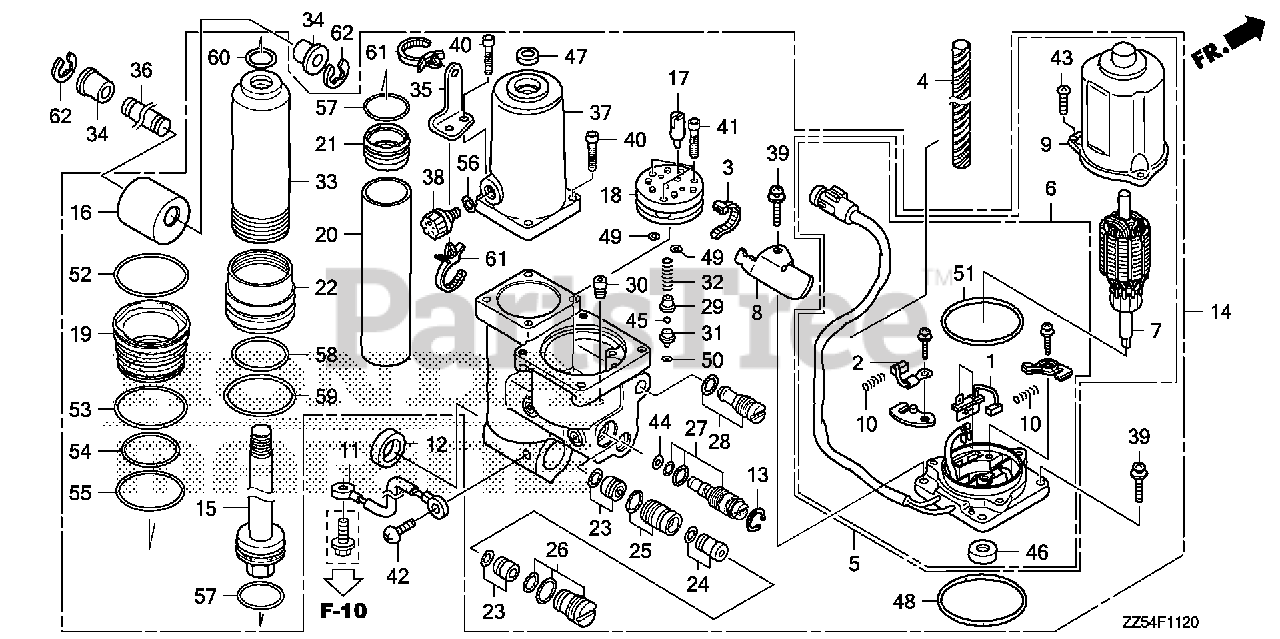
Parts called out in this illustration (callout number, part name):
1	BREAKER ASSY.
2	BRUSH ASSY.
3	BAND (BLACK 3.5X140)
4	TUBE, SPIRAL
5	MOTOR ASSY., POWER TILT
6	BRACKET ASSY.
8	CLAMP, WIRE
10	SPRING, MOTOR
11	WIRE, LEAD (1.5X116MM)
12	SPACER (19.4X6)
13	CIRCLIP (INNER) (16)
14	TRIM-TILT ASSY., POWER
15	ROD, PISTON
16	METAL, JOINT
17	JOINT, DRIVE
19	GUIDE, TUBE (OUTER)
21	PISTON, FREE
22	LOWER TILT CYLINDER
27	VALVE, MANUAL
29	GUIDE, SPRING
30	VALVE, SET
31	SEAT B, VALVE
32	SPRING, VALVE
33	TUBE (OUTER)
34	BUSH, CYLINDER (UPPER)
35	PLATE, SET
36	PIN, CYLINDER (UPPER)
38	CAP, OIL TANK
39	SCREW-WASHER
40	BOLT, SOCKET (5X0.8)
41	BOLT, SOCKET
42	SCREW, PAN (6X8)
43	SCREW, PAN (5X20)
44	WASHER, SEAL
45	BALL, STEEL
47	SEAL, WATER
48	O-RING (1.8X69.6)
49	O-RING (1.5X6.5)
50	O-RING (1.5X3.5)
51	O-RING (2.0X55.5)
52	O-RING (2.0X52.5)
53	O-RING (2.0X49.5)
54	O-RING (2.4X41.2)
55	O-RING (2.0X45.5)
56	O-RING (1.8X10.8)
57	O-RING (2.0X28.5)
58	O-RING (2.0X34.5)
59	O-RING (3.5X41.7)
60	O-RING (2.4X15.8)
61	CLIP, HARNESS BAND (145MM) (BLACK)
62	E-RING (10MM)
